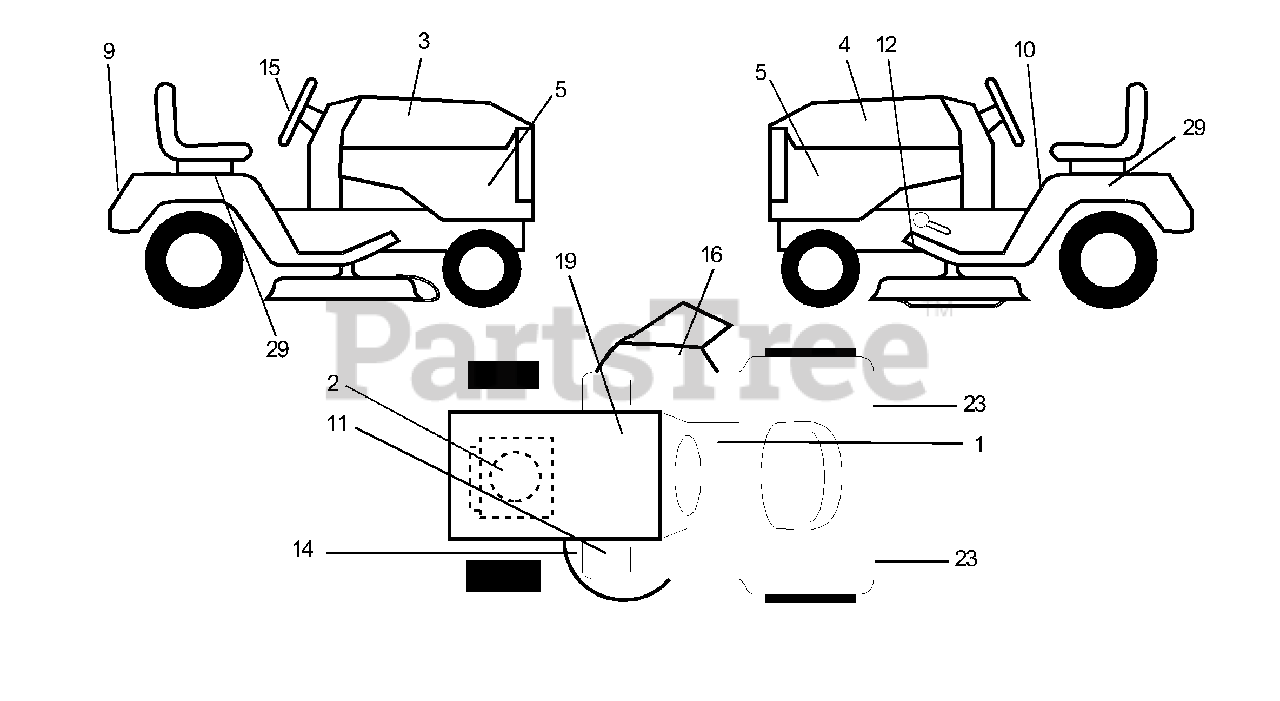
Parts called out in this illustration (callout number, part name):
1	Decal, Dash
2	Decal, Engine
3	Decal, Hood, RH
4	Decal, Hood, LH
5	Decal, Hood Side PNL
9	Decal, Fender
10	Decal, Danger
11	Decal, Clutch/Brake
14	Decal, V-Belt Schematic
15	Decal, Ins. Whl. Strg.
16	Decal, Housing Mower, Warning
19	Decal, Battery
23	Reflector, Taillight
29	Decal, Fender
30	Decal, Replacement Parts
